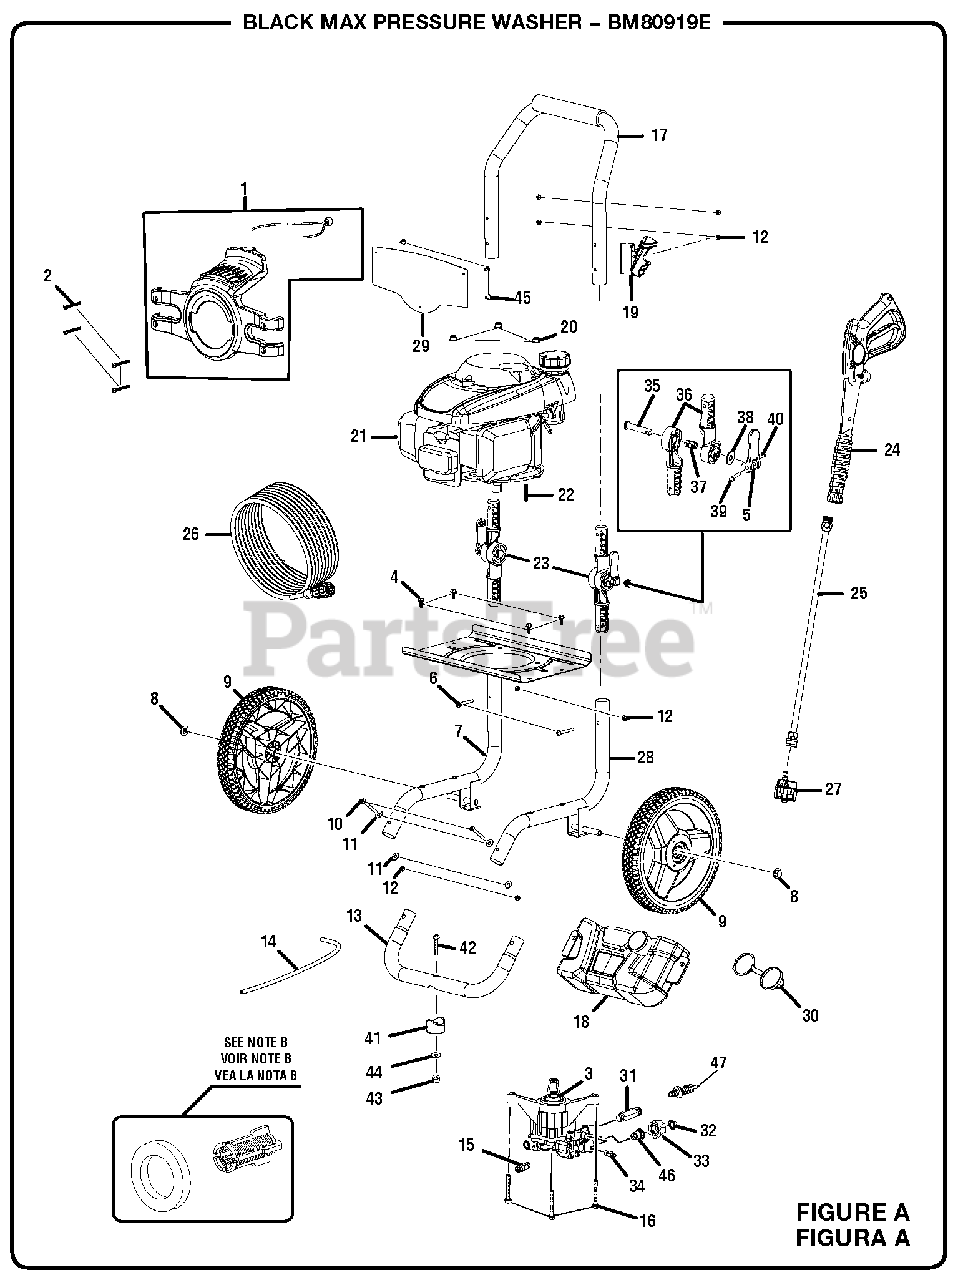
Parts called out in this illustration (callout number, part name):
1	Accessoires Panel and Bungee Cord
2	Screw (M6 x 48 mm, Button Hd.)
3	Pump Assembly
4	Bolt (M6 x 16 mm, Flange Hd.)
5	Lock Handle
6	Screw (M6 x 48 mm, T30 Torx Hd.)
7	Frame Assembly (Left)
10	Screw (M6 x 55 mm, T30 Torx Hd.)
11	Washer (1/4)
12	Lock Nut (M6)
13	Front Frame Assembly
14	Siphon Tube (350 mm)
15	Thermal Release Valve
16	Bolt (M8 x 60 mm, Flange Hd.)
17	Handle Assembly
18	Soap Tank
19	Upper Wand Holder
20	Flange Lock Nut (M8 x 1.25)
22	Output Shaft Key (40 mm)
23	Lock Lever Assembly
24	Trigger Handle Assembly
25	Spray Wand
26	Hose (25 Ft.)
27	6-in-1 Nozzle
28	Frame Assembly (Right)
29	Instruction Panel
30	Soap Tank Cap
31	Outlet Tube
32	Water Filter
34	Detergent Suction Kit
35	Locking Cam Pin
36	Lock Lever
37	Compression Spring
38	Washer (ID12 x OD30 x 2t)
39	Rotating Cam Pin
42	Screw (1/4-20 x 1.85 in, T30 Torx Pan Hd.)
43	Lock Nut (1/4-20)
44	Washer (1/4)
45	Screw (M3 x 5 mm, T10 Torx Pan Hd.)
47	Unloader Valve
